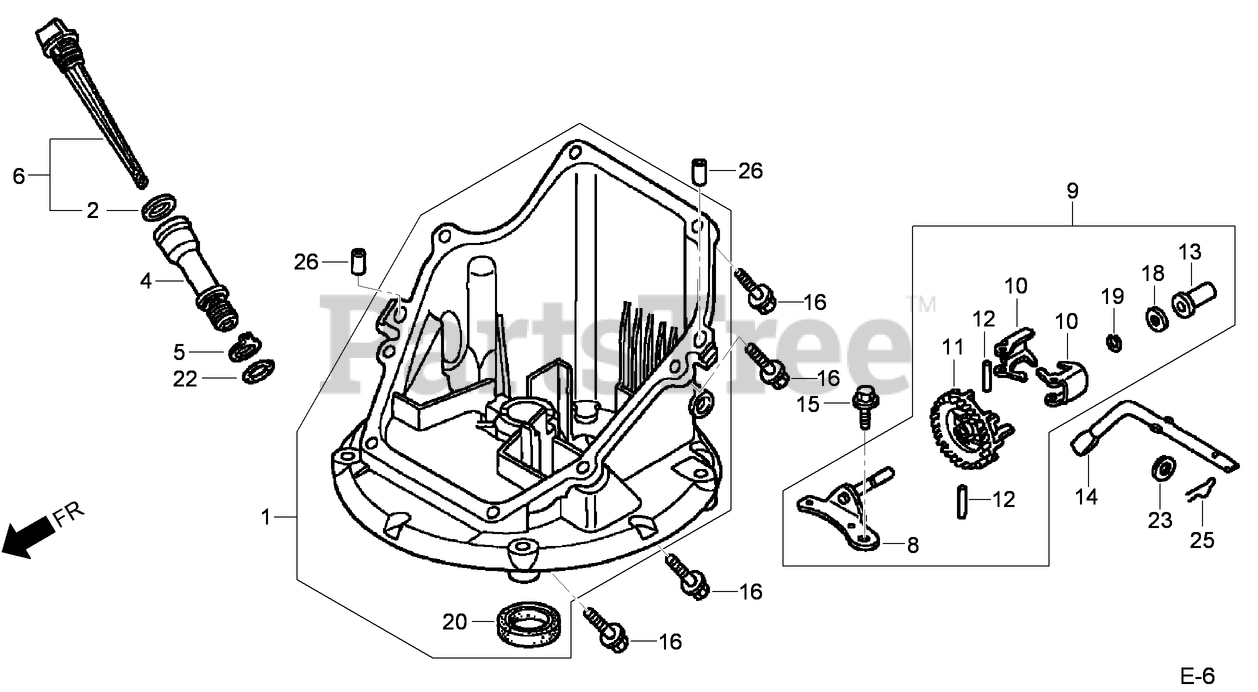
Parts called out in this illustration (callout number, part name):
1	OIL PAN ASM
2	GASKET-CAP, OIL FILLER
4	EXTENSION-FILLER, OIL
5	WASHER-LOCK, EXTENSION
6	OIL LEVEL GAUGE ASM
8	SHAFT-HOLDER, GOVERNOR
9	GOVERNOR ASM
10	WEIGHT-GOVERNOR
11	HOLDER-WEIGHT, GOVERNOR
12	PIN-WEIGHT, GOVERNOR
13	SLIDER-GOVERNOR
14	SHAFT-ARM, GOVERNOR
15	BOLT-FLANGE (6X14) (C T200)
16	BOLT-FLANGE (6X25) (C T 200)
18	WASHER-THRUST (6MM)
19	CLIP-HOLDER, GOVERNOR
20	SEAL-OIL (28X41.25X6)
22	O-RING (14.8X24) (N O K)
23	WASHER-PLAIN (6MM)
25	PIN-LOCK (8MM)
26	PIN-DOWEL (8X20)
